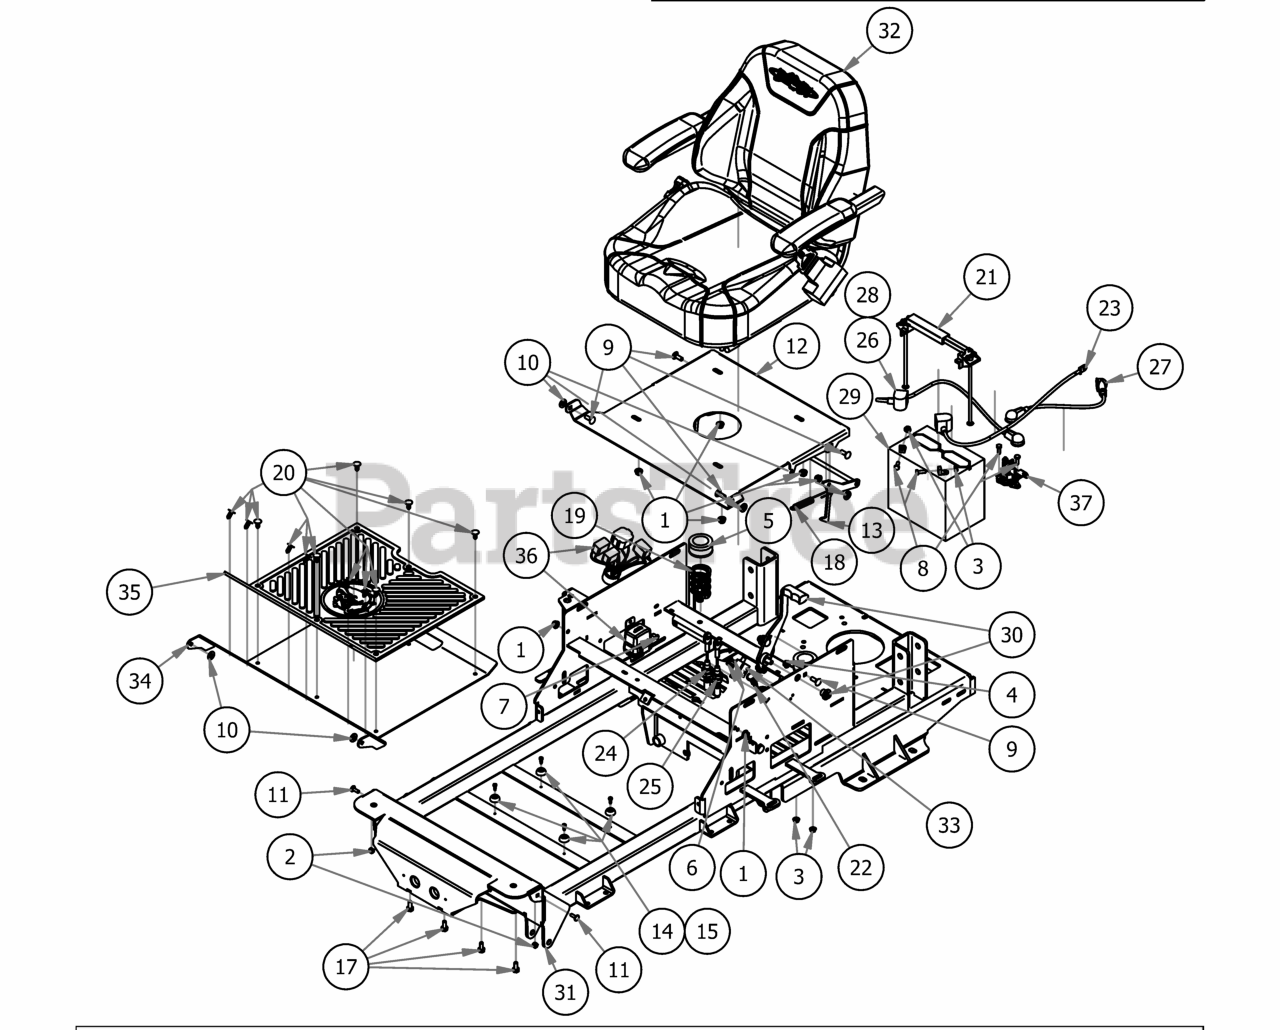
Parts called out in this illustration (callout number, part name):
1	5/16" Nylock Flange Nut
2	1/4" Nylock Nut
3	1/4-20 Hex Flange Nuts Zinc w/Serrations
4	5/16" Flange Nut
5	Seat Spring Cap Cover
6	12-24x 1/2 HWH Bolt
7	1/4" x 1/2" BS C/S 18-8 SS
8	1/4" x 3/4" Hex Bolt
9	5/16" x 7/8" Carriage Bolt
10	.360 ID Plastic Washer
11	1/4" x 3/4" Carriage Bolt
12	Seat Plate 2016
13	Seat Latch Rod Assembly
14	Button Bumper
15	#10 x 1/2" Self Tapping Screw
17	5/16 x 3/4 washer head type F screw
18	Seat Latch Spring
19	Seat Spring Assembly
20	Ratchet Fastener
21	Hold Down Assembly
23	Ground Cable
24	Brake Cable,18.5"
25	Brake Cable, 24.5"
26	24" Red Battery Cable
27	12" Red Battery Cable (Not on Honda)
28	36" Red Battery Cable (Honda Only)
30	2017 ZT Brake Handle Assembly
31	2016 Frame
32	2019 Maverick Seat
33	Safety Switch
34	2018 Maverick Floorboard
35	2017 MZ/ZT Floor Mat
36	Wiring Harness
37	Solenoid (Not used on Honda)
